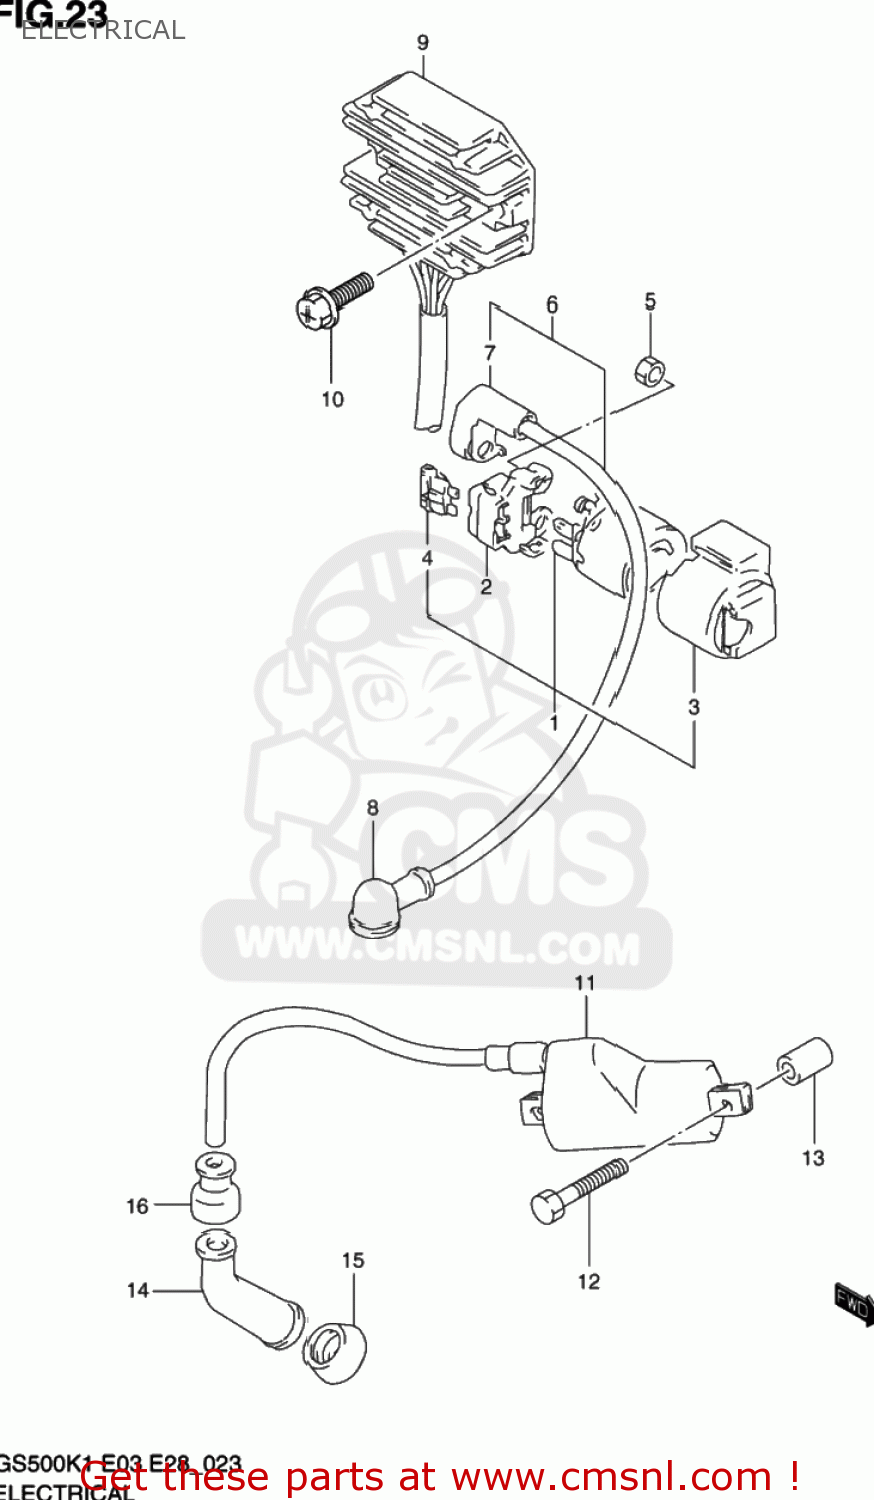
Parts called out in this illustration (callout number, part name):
1	RELAY ASSY,STARTING MOTOR
2	TERMINAL,RELAY
3	BRACKET,STARTING MOTOR RELAY
4	FUSE(20A)
5	NUT
6	WIRE,STARTER MOTOR LEAD
7	CAP,STARTER RELAY TERMINAL
8	CAP,STARTER MOTOR LEAD
9	RECTIFIER ASSEMBLY
10	BOLT
11	COIL ASSY,IGNITION
12	BOLT
13	SPACER(6.2X12X16)
14	CAP ASSY,SPARK PLUG
15	SEAL,SPARK PLUG CAP
16	SEAL,HIGH TENSION CORD
